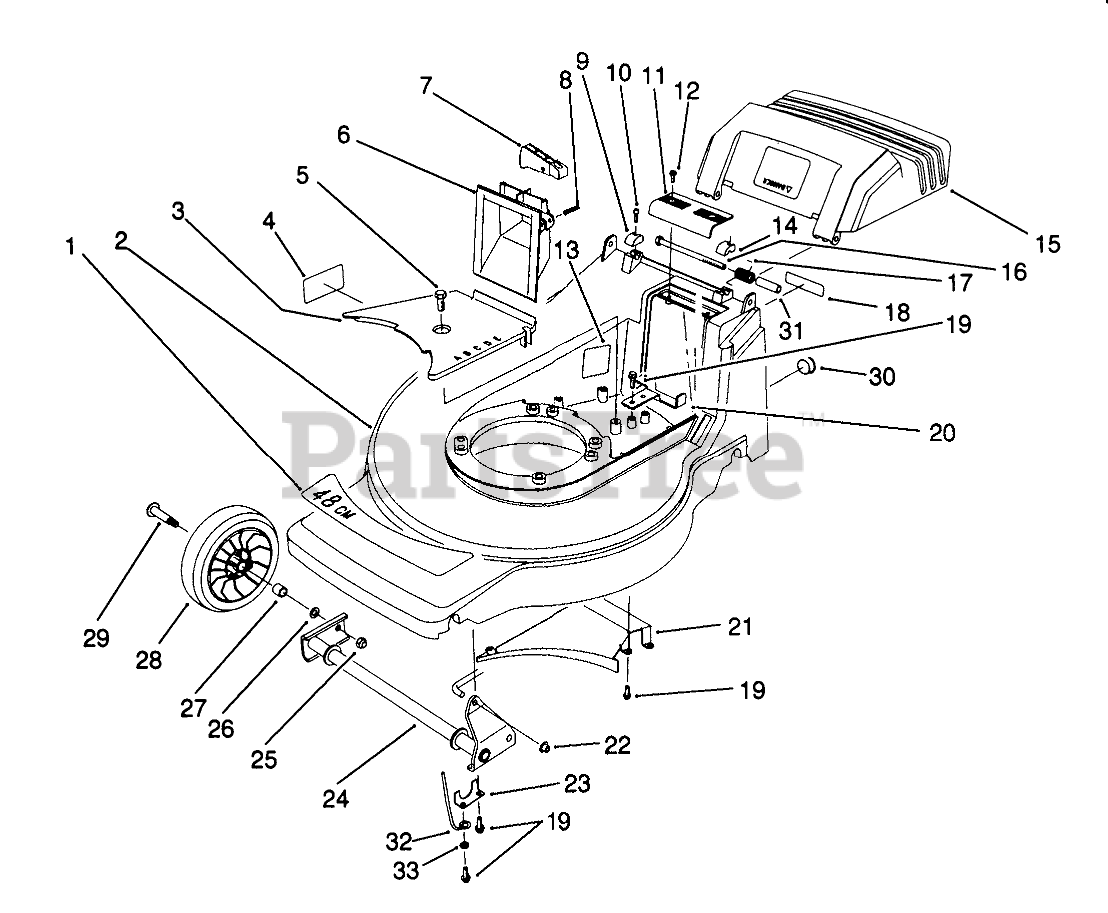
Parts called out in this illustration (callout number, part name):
1	DECAL - DECK
2	Housing-48cm
3	BELT COVER
4	Decal Danger
5	SCREW-HWHTF
6	GRIP - LOWER
7	TRIGGER - HOC
8	PIN-SPIRAL
9	CAP-HINGE BOLT, RH
10	SCREW-HSH
11	GRIP-UPPER
12	SCREW-PPH, PLASTITE
13	Decal-Noise
14	CAP-HINGE BOLT, LH
15	Door-Discharge
16	SCREW-HH
17	DOOR SPRING
18	DECAL FRENCH REGUL.
19	SCREW-HWHTF
20	REAR BELT GUIDE
21	Ramp-Discharge
22	NUT-PUSH
23	FRONT SECURING PLATE
24	FRONT PIVOT WA
25	Nut
26	WASHER
27	BUSHING
28	Wheel & Tire Assembly (Incl. Ref. #27)
29	BOLT-WHEEL
30	DOME PLUG (DP-1000)
31	SPACER-DOOR
32	LH AXLE RETAINER
33	WASHER-FLAT
